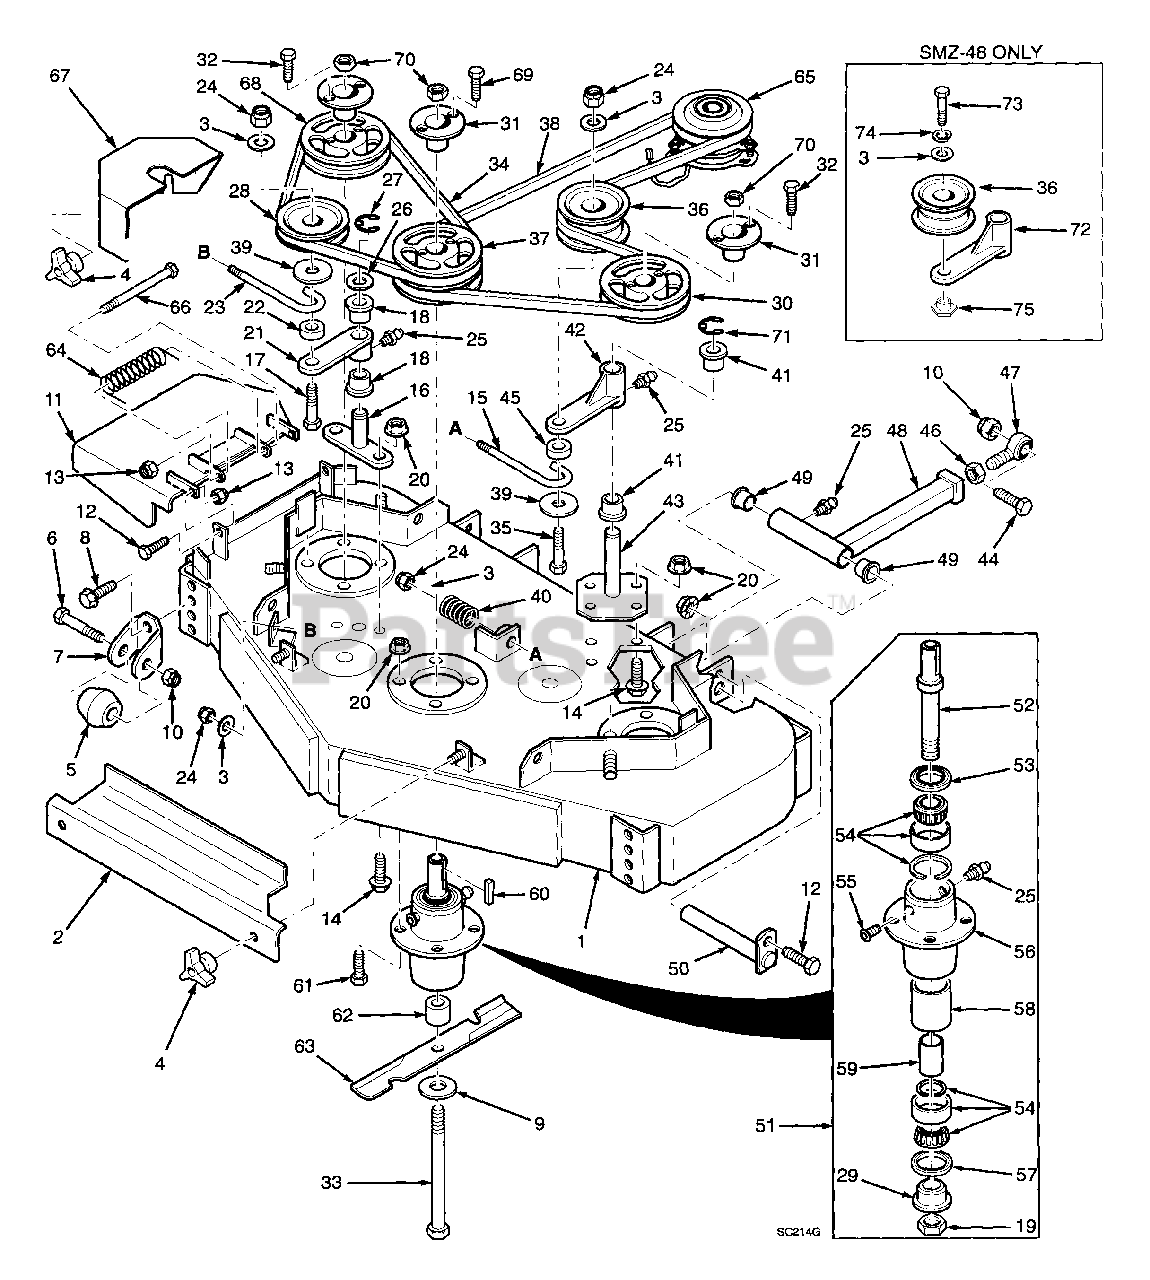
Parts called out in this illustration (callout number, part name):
1	Cutter Deck
2	Belt Cover, Front
3	Flatwasher, 3/8" Special (.391 x.938 x.105)
4	Wing Nut, 3/8-16
5	Anti-Scalp Wheel
6	Bolt, Hex Head 5/8-11 x 4-1/2"
7	Anti-Scalp Wheel Bracket
8	Bolt, Hex Serrated Flange 3/8-16 x 1"
9	Flatwasher, 5/8" (.688 x 1.75 x .134)
10	Nut, Hex Elastic Stop 5/8-11
11	Discharge Chute
12	Bolt, Hex Head 5/16-18 x 1"
13	Nut, Hex Elastic Stop 5/16-18
14	Bolt, Hex Serrated Flange 5/16-18 x 3/4"
15	"J" Rod
16	Idler Pivot Base
17	Bolt, Hex Head 3/8-16 x 2-1/4"
18	Bushing
19	Nut, Special 1-1/16-18
20	Nut, Hex Serrated Flange 5/16-18
21	Idler Arm
22	Spacer
23	"J" Rod
24	Nut, Hex Elastic Stop 3/8-16
25	Grease Fitting
26	Flatwasher, 3/4"
26	Flatwasher, 3/4" Special
27	Ring, Retaining 3/4" External "E"
28	Pulley, idler
29	Spindle Bushing, Bottom
30	Pulley, LH Spindle
31	Tapered Hub, 1-1/8 Bore
32	Bolt, Hex Head 1/4-20 x 3/4"
33	Bolt, Hex Head 5/8-11 x 9-1/2"
34	Belt, RH Blade Drive
35	Bolt, Hex Head 3/8-16 x 4-1/2"
36	Pulley, Idler Gutter Engagement
37	Pulley, Double Groove
38	Belt, Blade Drive
39	Flatwasher, 3/8" (.375 x 1.5 x .06)
40	Spring, Idler Tension
41	Bushing
42	Idler Arm
43	Idler Pivot Base
44	Bolt, Hex Head 5/8-11 x 3"
45	Spacer
46	Nut, Hex 5/8-18 UNF
47	Rod End
48	Push Arm
49	Bushing
50	Push Arm Shaft
51	Spindle Assembly
52	Spindle Shaft
53	Seal, Top
54	Bearing Assembly
55	Relief Fitting, Tapered Spindle
56	Spindle Housing
57	Seal,Bottom
58	Spacer, Outside
59	Spacer, Inside
60	Key, 1/4 x 1/4 x 2"
61	Bolt, Hex Head 5/16-18 x 1-1/4"
62	Spacer, Tapered Spindle
63	Cutter Blade, 21" Standard
63	Cutter Blade, 21" High Lift
64	Spring, Discharge Chute
65	Electric Clutch
66	Bolt, Hex Head 5/16-18 x 4.25"
67	Belt Cover, LH
68	Pulley, RH Spindle
69	Bolt, Hex Head 1/4-20 x 1.375
70	Nut, Hex 5/8-11 UNC
71	Ring, Retaining 1-1/8" External "E"
72	Idler Arm
73	Bolt, Hex Head 3/8-16 X 3-3/4"
74	Lockwasher 3/8
75	Nut, 3/8-16 Special W/Washer
